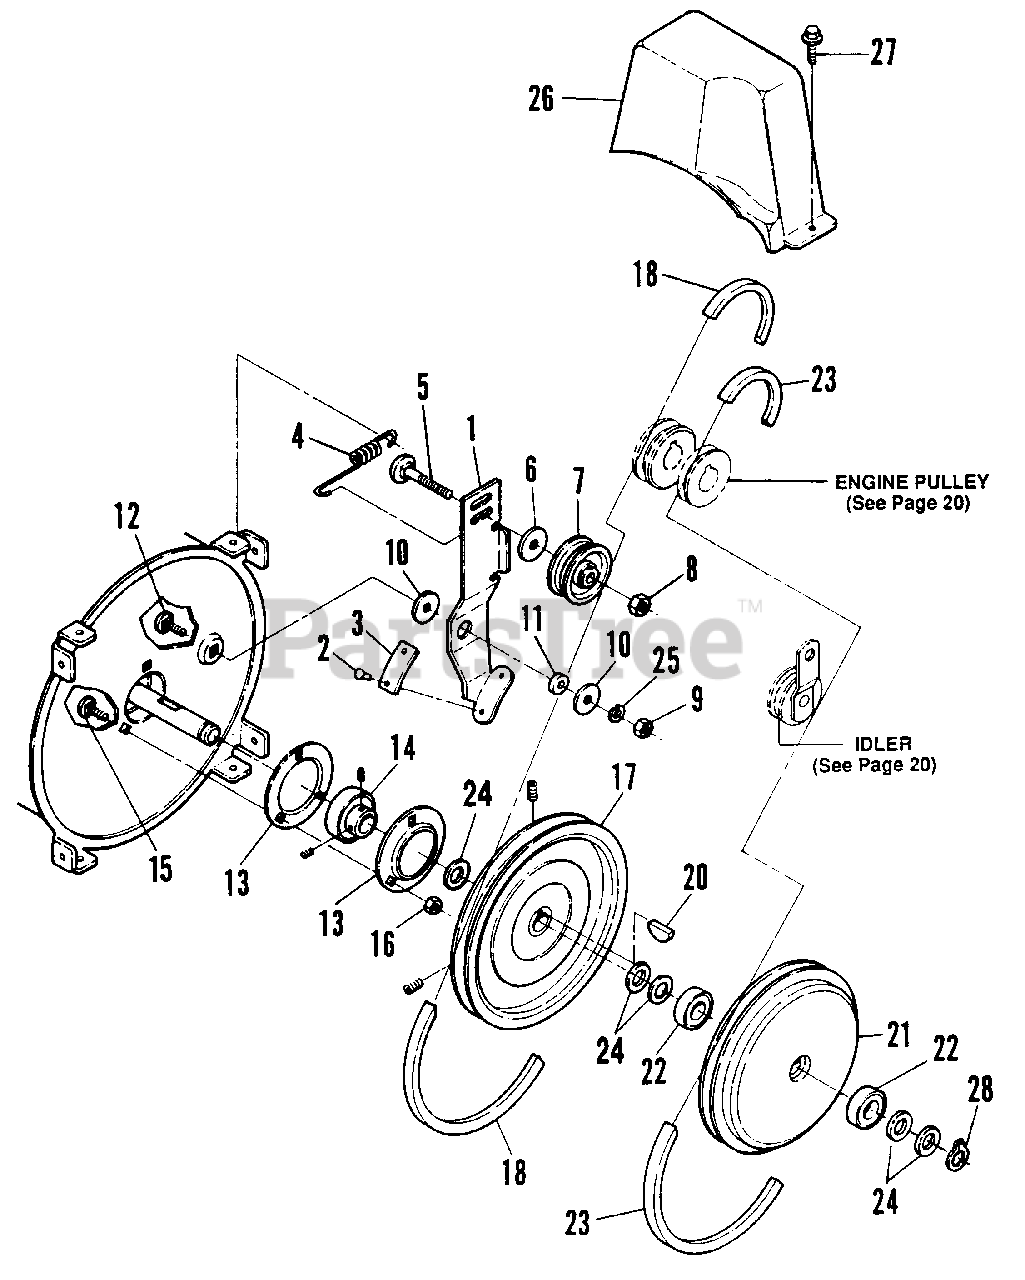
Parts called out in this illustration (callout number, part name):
1	ASSEMBLY, Idler Arm
2	RIVET, 3/16 x .344
3	PAD, Brake
4	SPRING
5	BOLT, 3/8-16 x 1-1/2" Carriage
6	WASHER, 3/8" Flat
7	PULLEY, Idler
8	NUT, 3/8-16 Hex
9	NUT, 5/16-18 Hex
10	WASHER, 5/16" x 1-1/4" x 3/32" Flat
11	SPACER
12	BOLT, 5/16-18 x 1" Carriage
13	HOUSING, Bearing
14	BEARING
15	BOLT, 5/16-18 x 3/4" Carriage
16	NUT, 5/16-18 Hex Flange Lock
17	SHEAVE, Blower
18	BELT, Blower, 38.5" 4L, 8 HP
20	KEY, 3/16 x 7/8" Woodruff
21	PLATE, Drive
22	BEARING, Ball
23	BELT, Traction, 37.75" 3L, 8 HP
24	WASHER, 1/2 Shim
25	WASHER, 5/16 Split Lock
26	COVER, Belt Guard
27	SCREW, 1/4-20 x 3/8" Self-Tapping
28	RETAINING RING, 1/2
